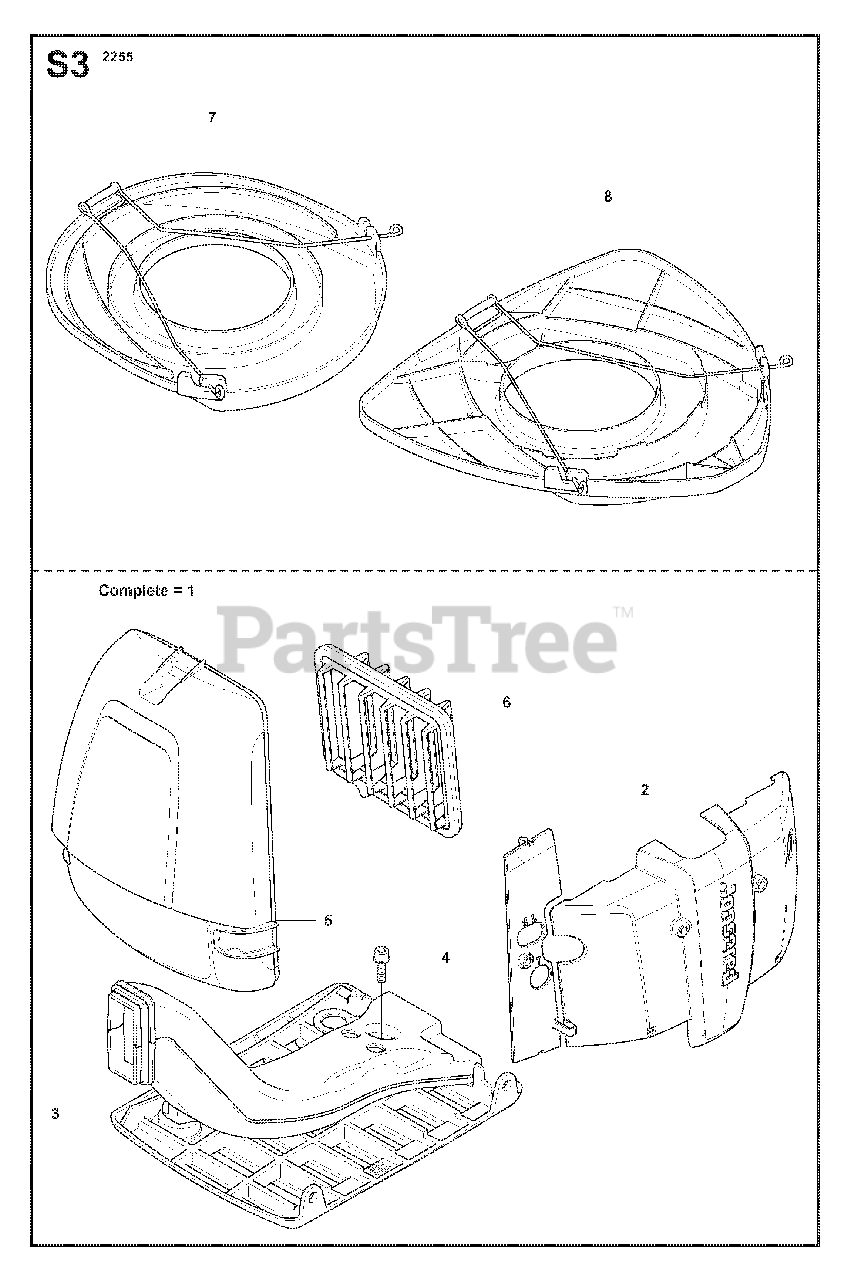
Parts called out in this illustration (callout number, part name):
6	FILTER
7	BLADE GUARD TRANSPORT
8	TRANSPORT GUARD
